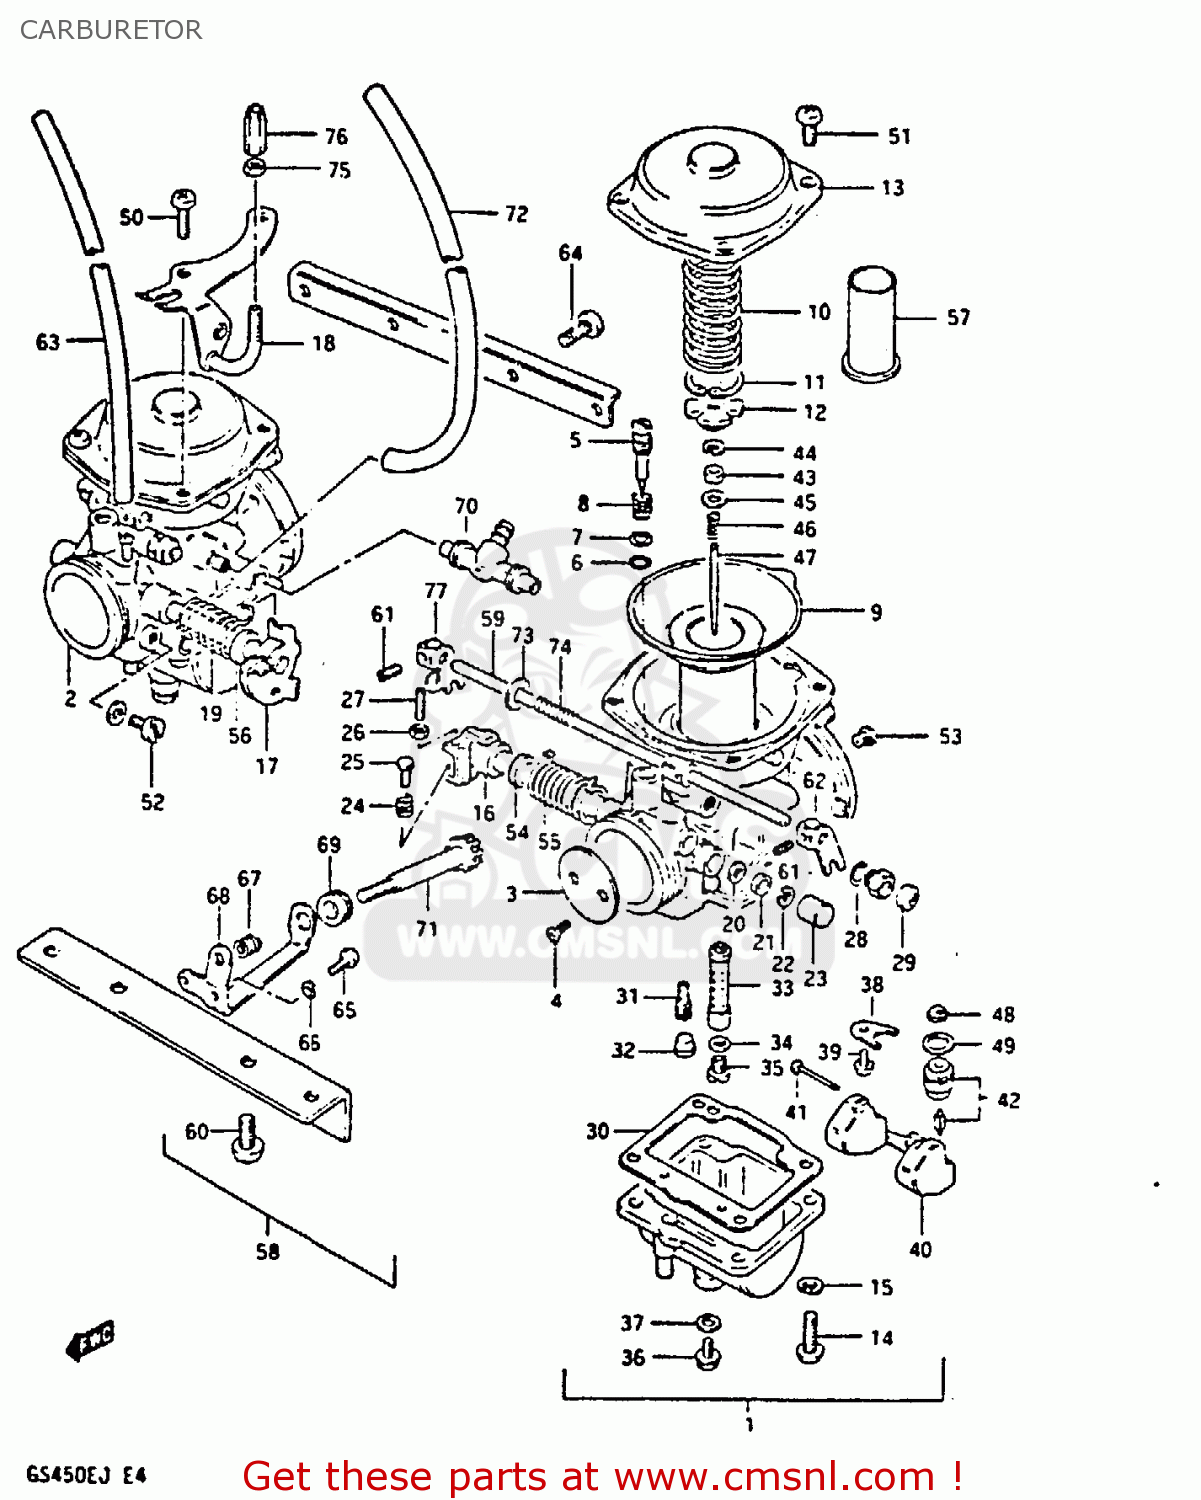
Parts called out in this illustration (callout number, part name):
1	CARBURETOR ASSY, LH
2	CARBURETOR ASSY, RH
3	VALVE, THROTTLE
4	SCREW
5	SCREW,PILOT AIR
6	O RING,PILOT AIR SCREW
7	WASHER
8	SPRING
9	DIAPHRAGM ASSY
10	SPRING
11	E RING
12	HOLDER,GUIDE
13	COVER
14	SCREW
15	LOCK WASHER
16	SHAFT ASSEMBLY
17	SHAFT,THROTTLE
18	BRACKET,THROTTLE CABLE
19	SPRING
20	SEAL
21	GASKET,THROTTLE SHAFT (NAS)
22	E RING
23	CAP
24	SPRING,THROTTLE SCREW
25	PIN,THROTTLE LEVER
26	NUT
27	SCREW
28	O RING
29	CAP,STARTER VALVE
30	GASKET,FLOAT CHAMBER (NAS)
31	JET,PILOT(45)
32	PLUG,NEEDLE JET
33	JET,NEEDLE(R-0)
34	WASHER,NEEDLE NOZZLE
35	JET,MAIN(120)
36	PLUG,DRAIN
37	GASKET (NAS)
38	PLATE,NEEDLE VALVE FITING
39	SCREW
40	FLOAT
41	PIN,FLOAT
42	VALVE ASSY,NEEDLE
43	RING
44	CLIP
45	WASHER,JET NEEDLE
46	SPRING
47	NEEDLE, JET
48	FILTER
49	O-RING,NEEDLE VALVE
50	SCREW 5X10
51	SCREW
52	SCREW
53	JET,AIR(135)
54	SPACER,THROTTLE SHAFT
55	SPRING
56	SPACER,THROTTLE SHAFT
57	RING
58	FLANGE ASSEMBLY,CARBURETOR
59	SHAFT,STARTER
60	SCREW
61	SCREW
62	LEVER
63	HOSE 4.5X8X600
64	SCREW 5X12
65	SCREW
66	LOCK WASHER
67	SPRING,THROTTLE ADJUST
68	BRACKET,THROTTLE ADJUST
69	CAP,RUBBER
70	NIPPLE,CARBURETOR
71	SCREW
72	HOSE
73	SPRING
74	SPRING,STARTER
75	NUT
76	ADJUSTER
77	LEVER,STARTER
